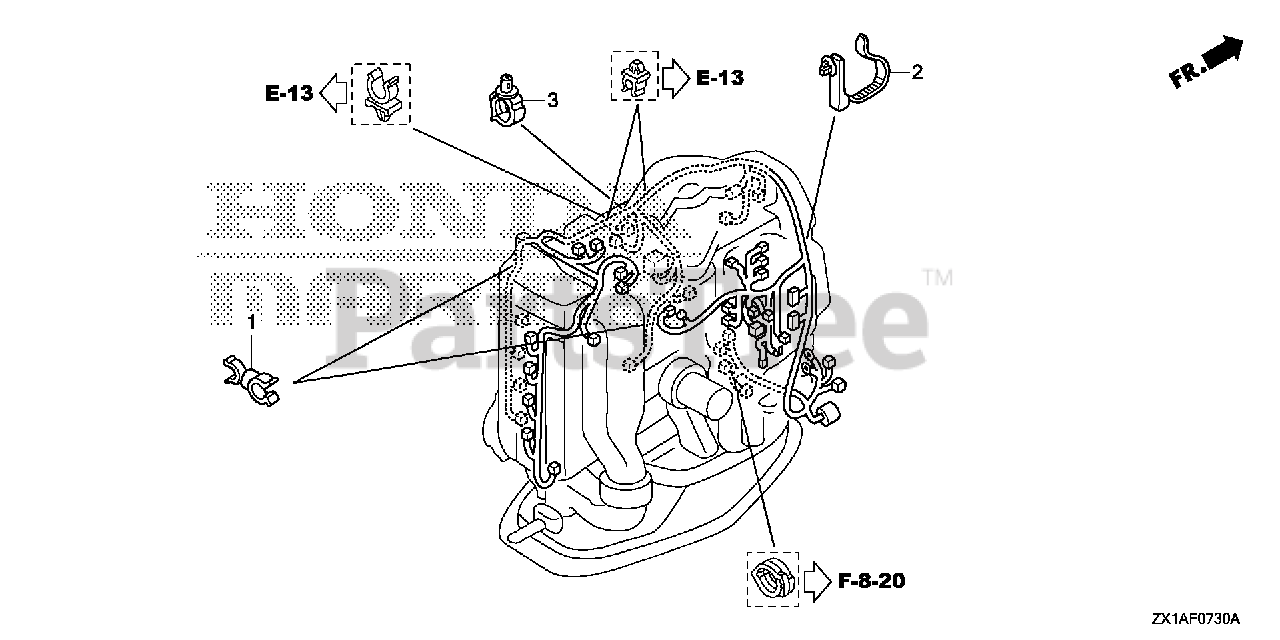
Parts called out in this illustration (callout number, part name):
1	CLAMP, HOSE
2	BAND, HARNESS OFFSET (10) (122.5MM) (BROWN)
3	CLAMP, ENGINE SUB-WIRE
